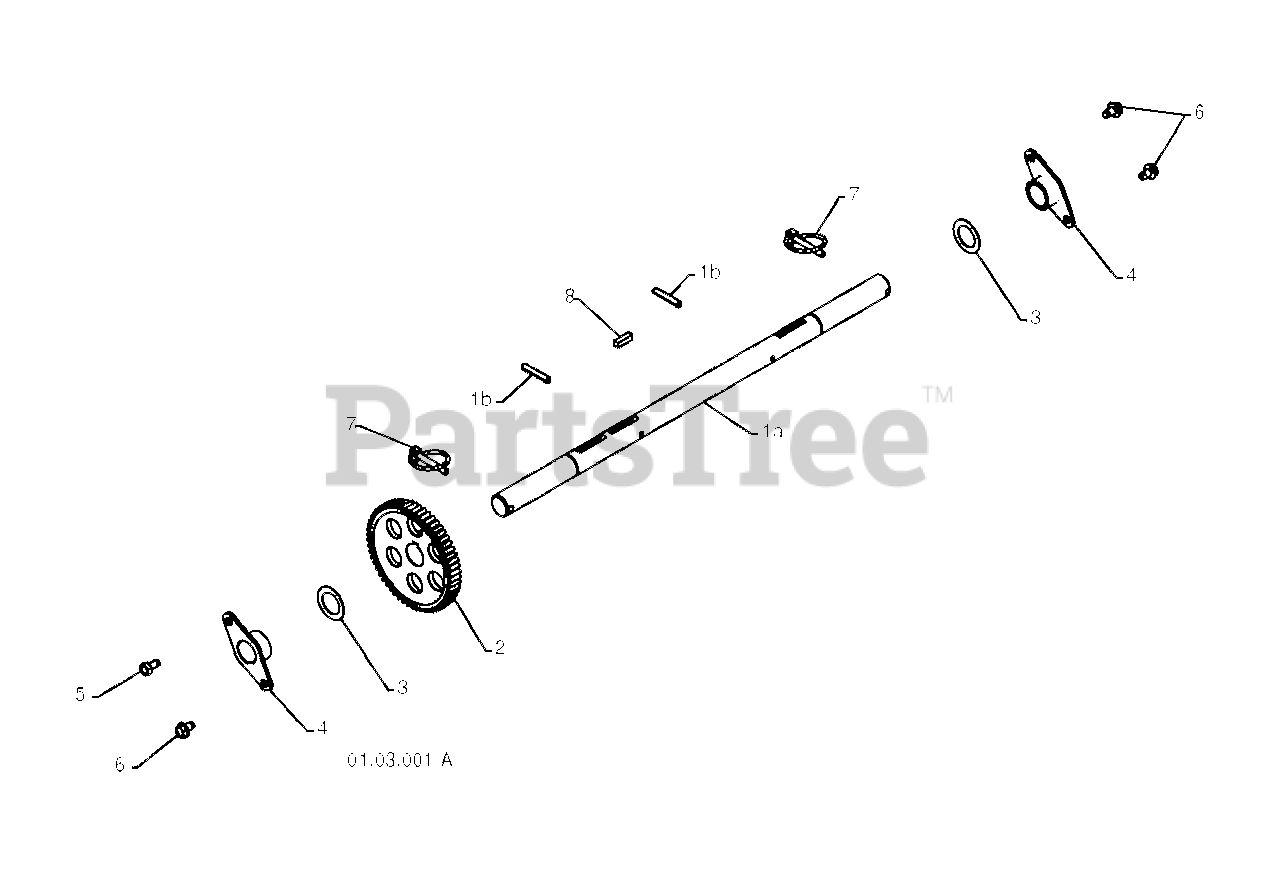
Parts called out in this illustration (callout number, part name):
1	AXLE.ASM.SHAFT.W/ROLLPIN.PS
1A	SHAFT.AXLE.POWER.STEERING
1B	PIN.ROLL.3/16
2	GEAR, AXLE (58T)
3	WASHER TRUST 1"
4	BEARING, AXLE
6	SCREW LT
7	PIN KLIK, 1/4
8	KEY, SQUARE 1/4 X .875
